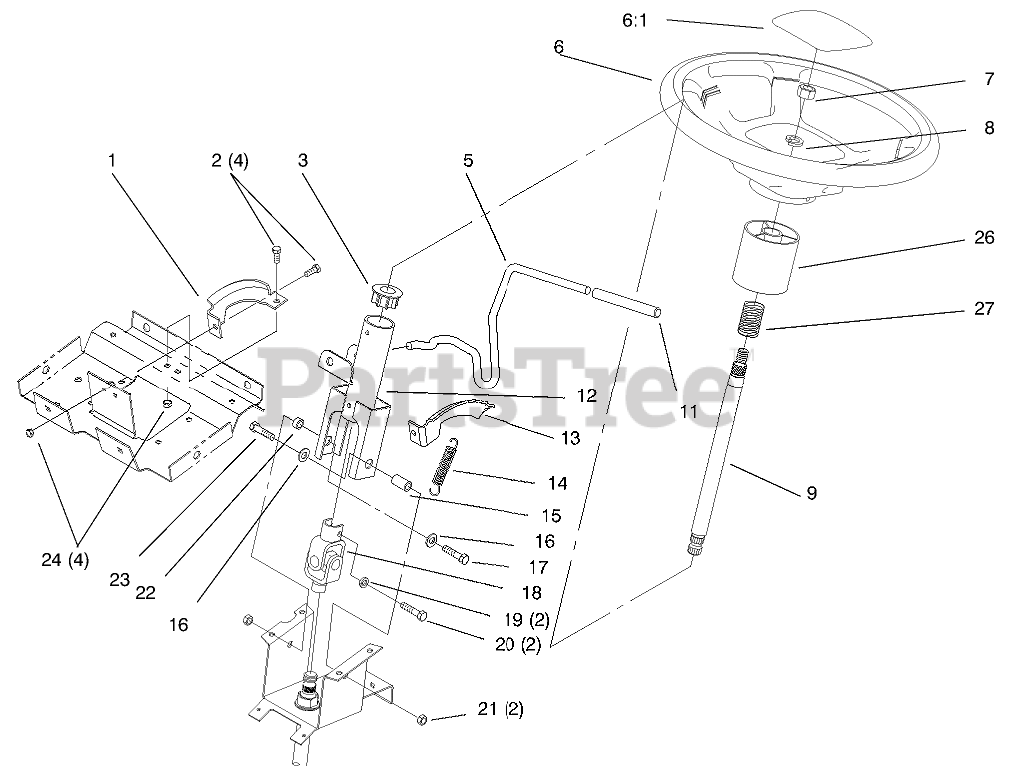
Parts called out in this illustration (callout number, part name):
1	BRACKET-SUPPORT, COLUMN
2	SCREW-HH
3	BUSHING-STEERING, UPPER
4	WASHER-BOWED
5	LEVER-TILT
6	Wheel-Steering
6:1	COVER-WHEEL
7	NUT-HH
8	WASHER-LOCK
9	SHAFT-SHORT, STEERING
10	WASHER-FLAT
11	CAP-ROD, TILT
12	COLUMN ASM
13	BRACKET-DETENT
14	SPRING-EXTENSION
15	SPACER-YOKE
16	WASHER-PLAIN
17	SCREW-HH
18	U-JOINT, STEERING
19	WASHER-LOCK
20	SCREW-CAP, HH
21	NUT-LOCK, NI
22	SPACER-YOKE, RIGHT
23	SCREW-HH
24	NUT-HEX
